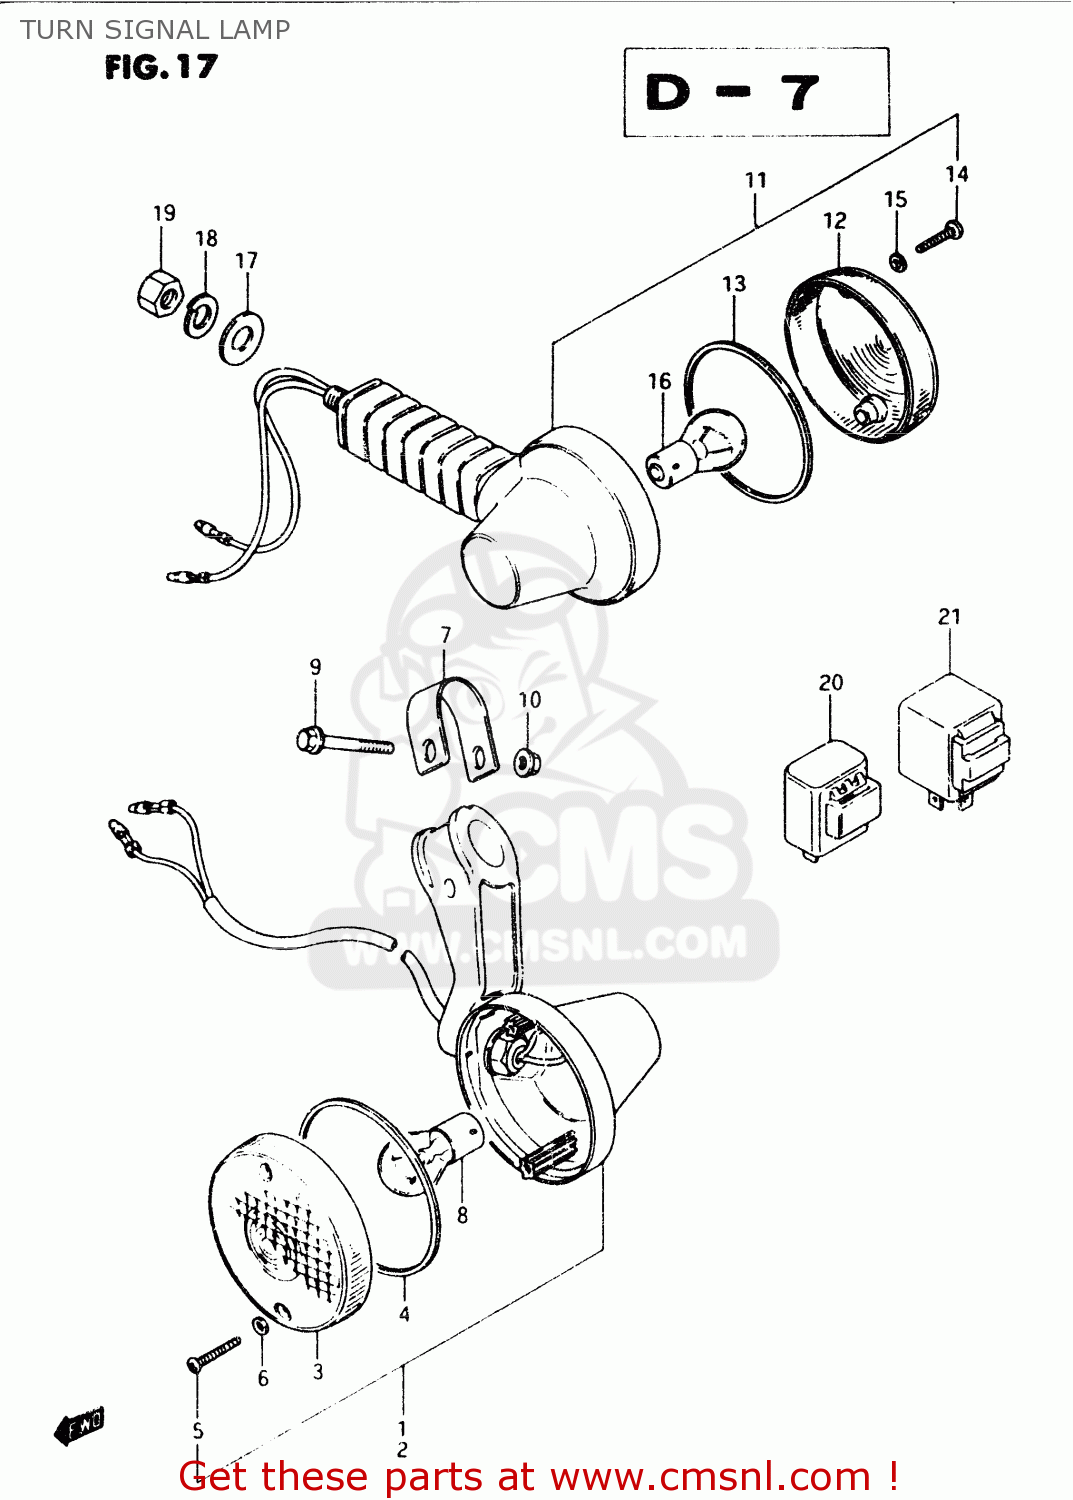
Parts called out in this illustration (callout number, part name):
1	LAMP ASSEMBLY,FRONT TURN SIGNAL
2	LAMP ASSY,FR TURN SIGNAL,L
3	LENS
4	GASKET (NAS)
5	SCREW ,4X25
6	GASKET (NAS)
7	PLATE
8	BULB(12V21W)
9	BOLT 5X42
10	NUT
11	LAMP ASSY, REAR TURNSIGNAL
12	LENS
13	GASKET (NAS)
14	SCREW
15	GASKET (NAS)
16	BULB(12V21W)
17	WASHER (12.5X26X1.6)
18	WASHER
19	NUT
20	RELAY ASSEMBLY,TURN SIGNAL
21	RELAY ASSY,TUR
